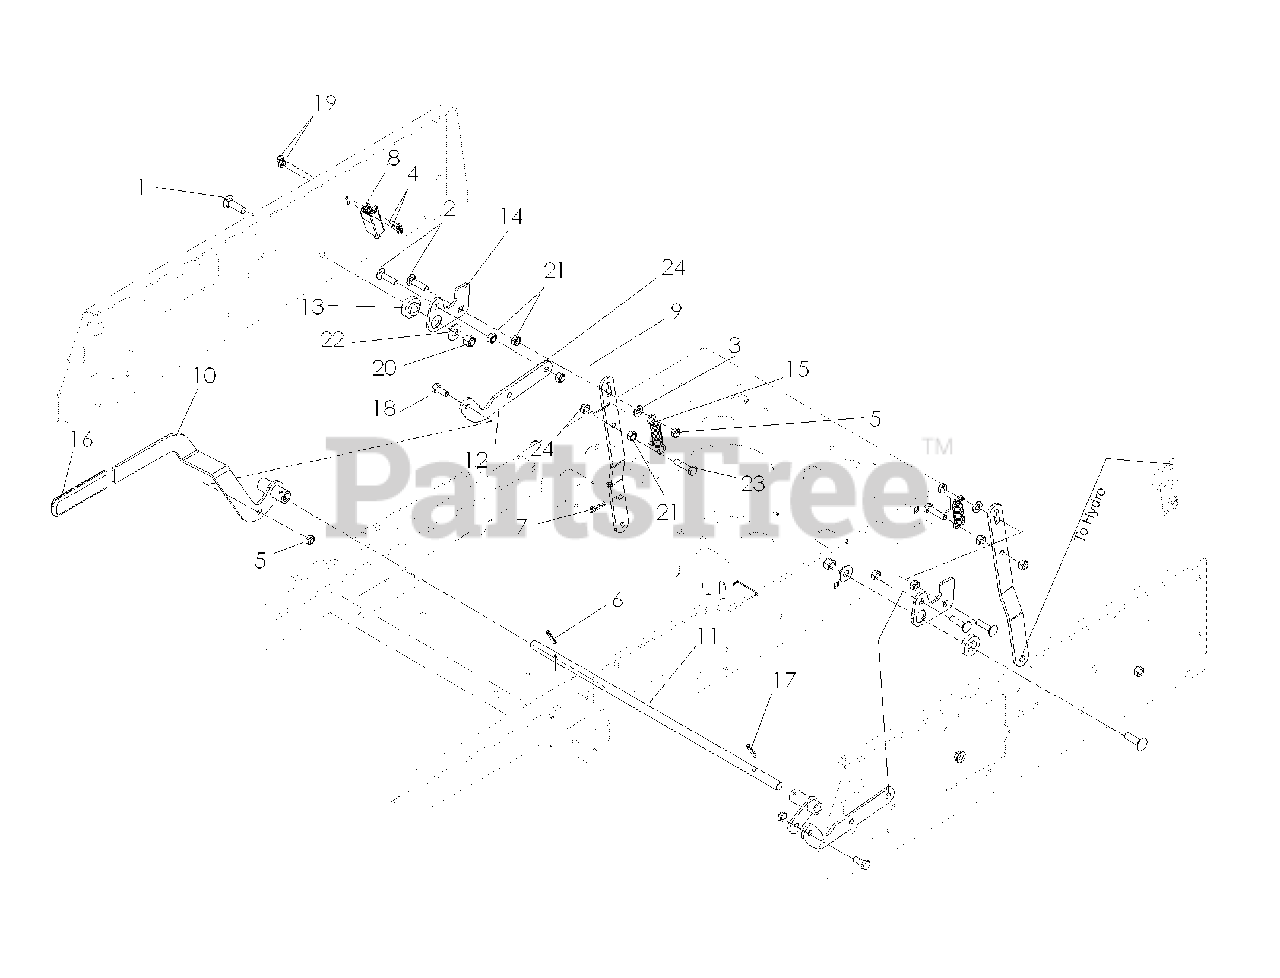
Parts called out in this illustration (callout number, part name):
1	RHSNB 3/8-16 X 1-1/4
2	BOLT, CARRIAGE 5/16X1-1/4
3	FLAT WASHER 5/16 SAE
4	SCREW #10-24 X 5/8
5	5/16-18 THIN PROF NY
6	ROLL PIN 3/16 X 1-1/4 ZD
7	COTTER HP .08 DIA X 1.19
8	SWITCH, INTERLOCK
9	LWR BRAKE LINK
10	BRAKE HANDLE DRILLED
11	BRAKE ROD
12	UPPER BRAKE LINK
13	BRAKE ARM PIVOT
14	BRAKE PIVOT
16	GRIP BRAKE HANDLE
17	BRAKE ARM DRILLED BLK
18	HCS 5/16C X 3/4
19	NUT 10-24 NYLOC
20	NUT 3/8-16 NYLOC
21	NUT 5/16C HEX
22	WASHER 3/8 FLAT
23	HCS 5/16C X 1 1/4
24	NUT 5/16 NYLOC
